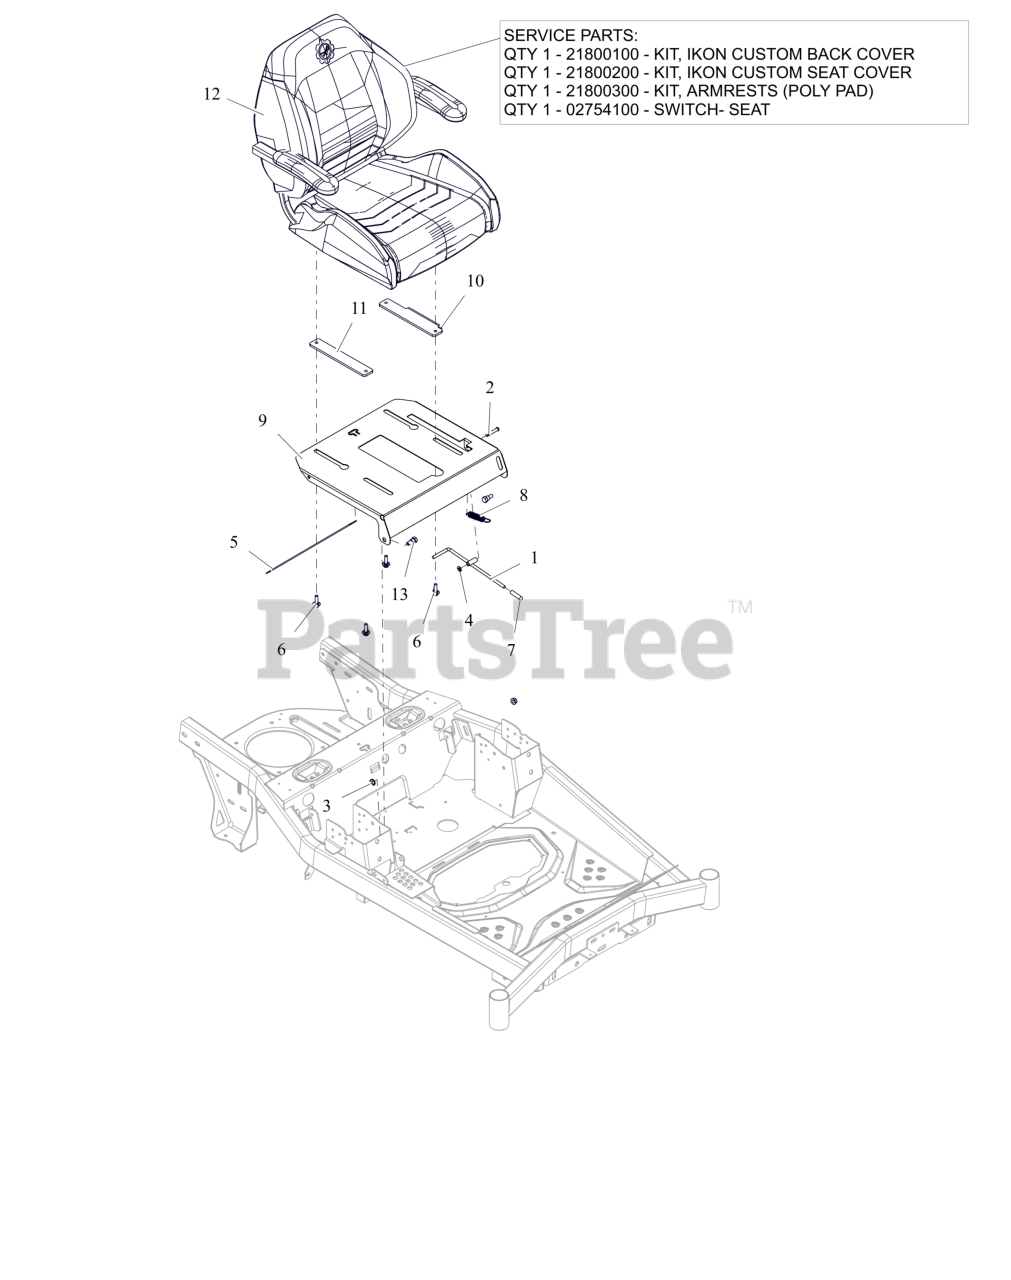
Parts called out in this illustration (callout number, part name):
1	WLDMT, LATCH SEAT (BLACK)
2	PIN, CLEV .309X1.75 ZCC
3	NUT-LK-CTR-FLG .375-16 GF ZCC
4	NUT-PUSH .312
5	LANYARD, SEAT CABLE .093X19.5
6	BLT, SHLDR .31-18 X .100
7	GRIP, BLACK RD-.312X1.50
8	SPRG, EXTENSION .063 X .653 X 2.755
9	PLATE-SEAT
10	PLATE- SEAT ADJUSTER
11	SPCR- SEAT PLATE
12	SEAT- IKON 2023 (WOOD)
12	KIT - IKON CUSTOM BACK COVER
12	KIT - IKON CUSTOM SEAT COVER
12	KIT - ARMRESTS (POLY PAD)
12	SWITCH- SNAP MTG N.O.
13	BLT-SHLDR .50X.38 ZCC
